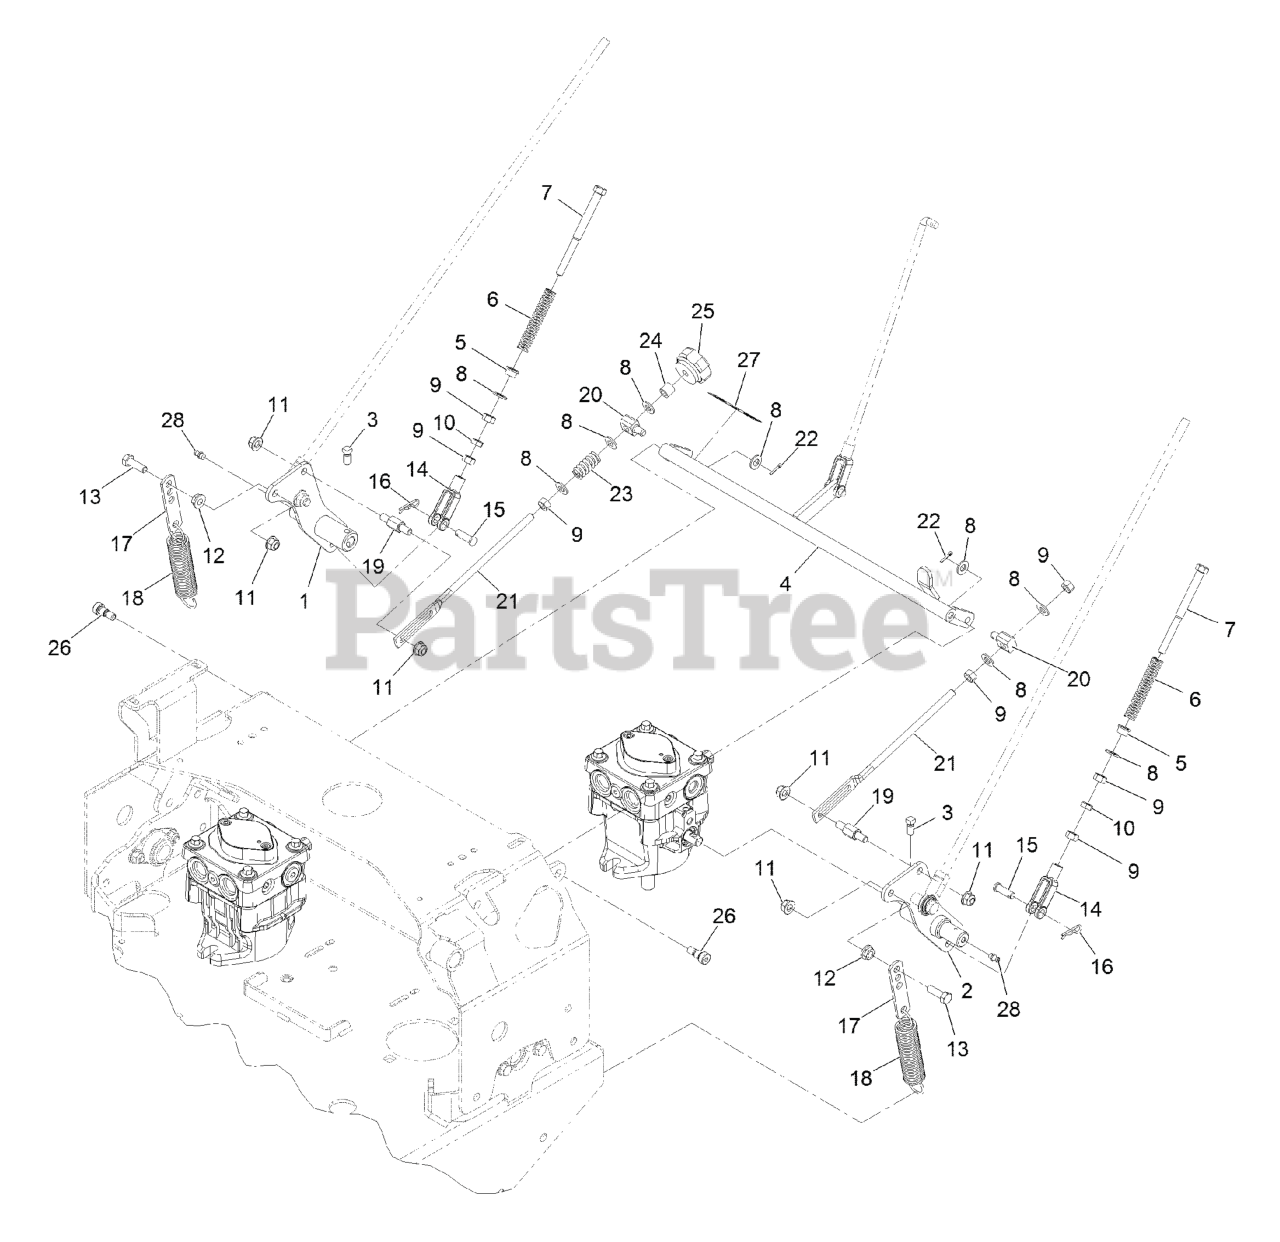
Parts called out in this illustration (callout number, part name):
1	WELD, MOTION CONTROL, RT
2	WELD, MOTION CONTROL, LT
3	SCREW-SET
4	WELD, SPEED CONTROL
5	BUSHING-FLANGED
6	SPRING,COMPRESSION (NEUT)
7	BOLT-RETURN, NEUTRAL
8	WASHER-PLAIN
9	NUT-HEX
10	NUT-JAM
11	NUT-HF, NI
13	SCREW-HH
14	YOKE-ADJUSTABLE
15	PIN-CLEVIS
16	PIN-COTTER
17	TAB-SPRING, EXTENSION
18	SPRING-EXTENSION
19	PIN, MOTION CONTROL
20	SWIVEL-ADJUSTABLE, SHORT
21	LINK-CONTROL, SPEED
22	PIN-COTTER
23	SPRING-COMPRESSION
25	KNOB-TRACKING
26	SCREW-HSH
27	DECAL-TRACKING ADJUSTMENT
28	FITTING-GREASE
